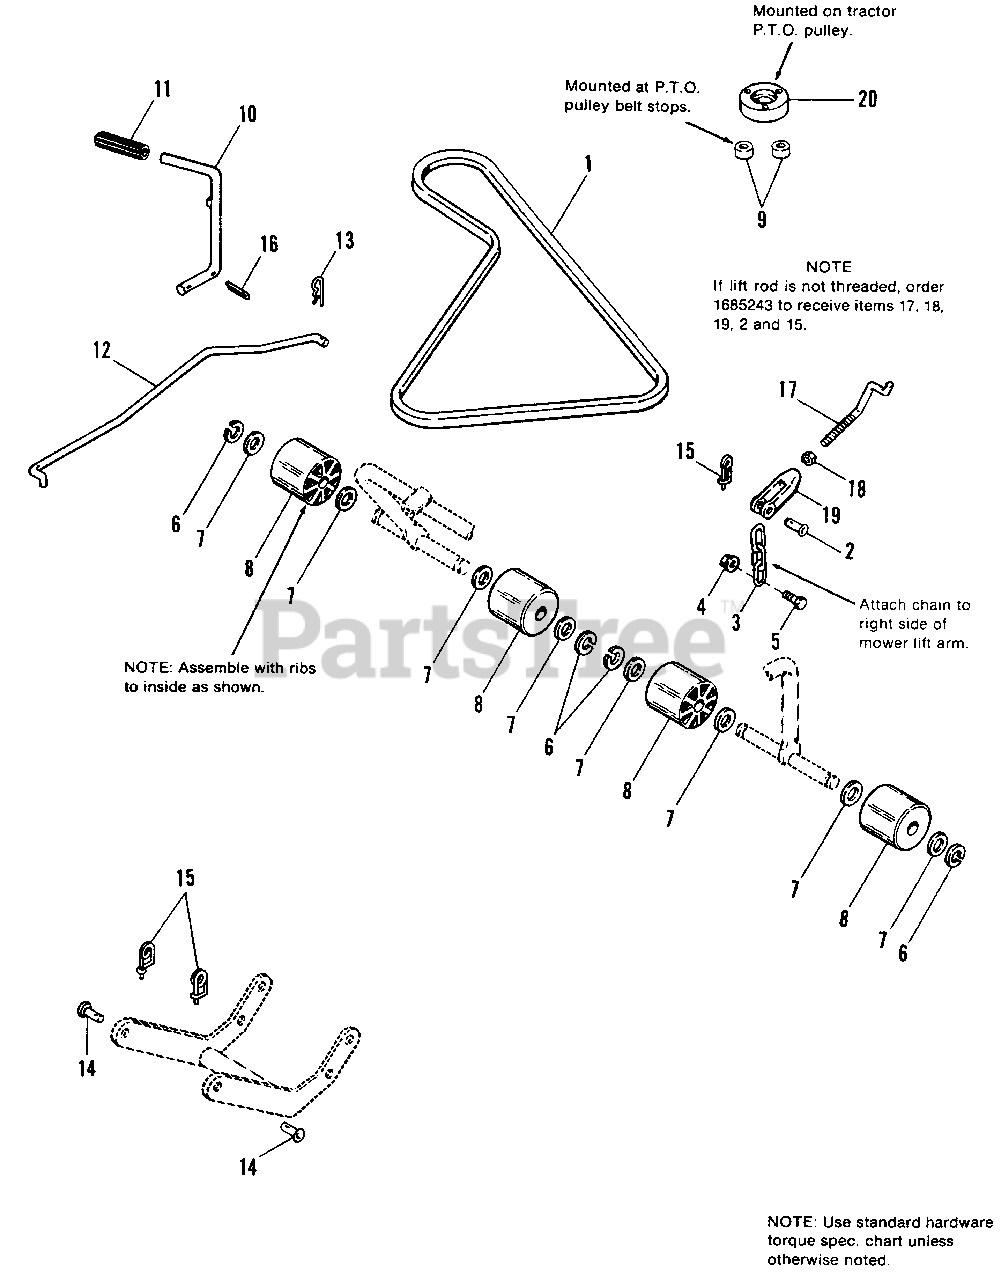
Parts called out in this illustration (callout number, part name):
1	V-BELT, Mower Drive
2	PIN, Rivet
3	CHAIN, Lift
4	LOCKNUT, Hex, Flange, 5/16-18
5	CAPSCREW, Hex Hd., 5/16-18 x 1
6	RING, Retaining
7	WASHER, Plain, 5/8
10	LEVER, Control
11	GRIP, Handle
12	ROD, P.T.O.
13	CLIP, Spring
15	CLIP, Pin, Safety
16	PIN, Cotter, 1/8 x 1
18	NUT, Jam, 5/16-18
20	SPACER, Pulley
